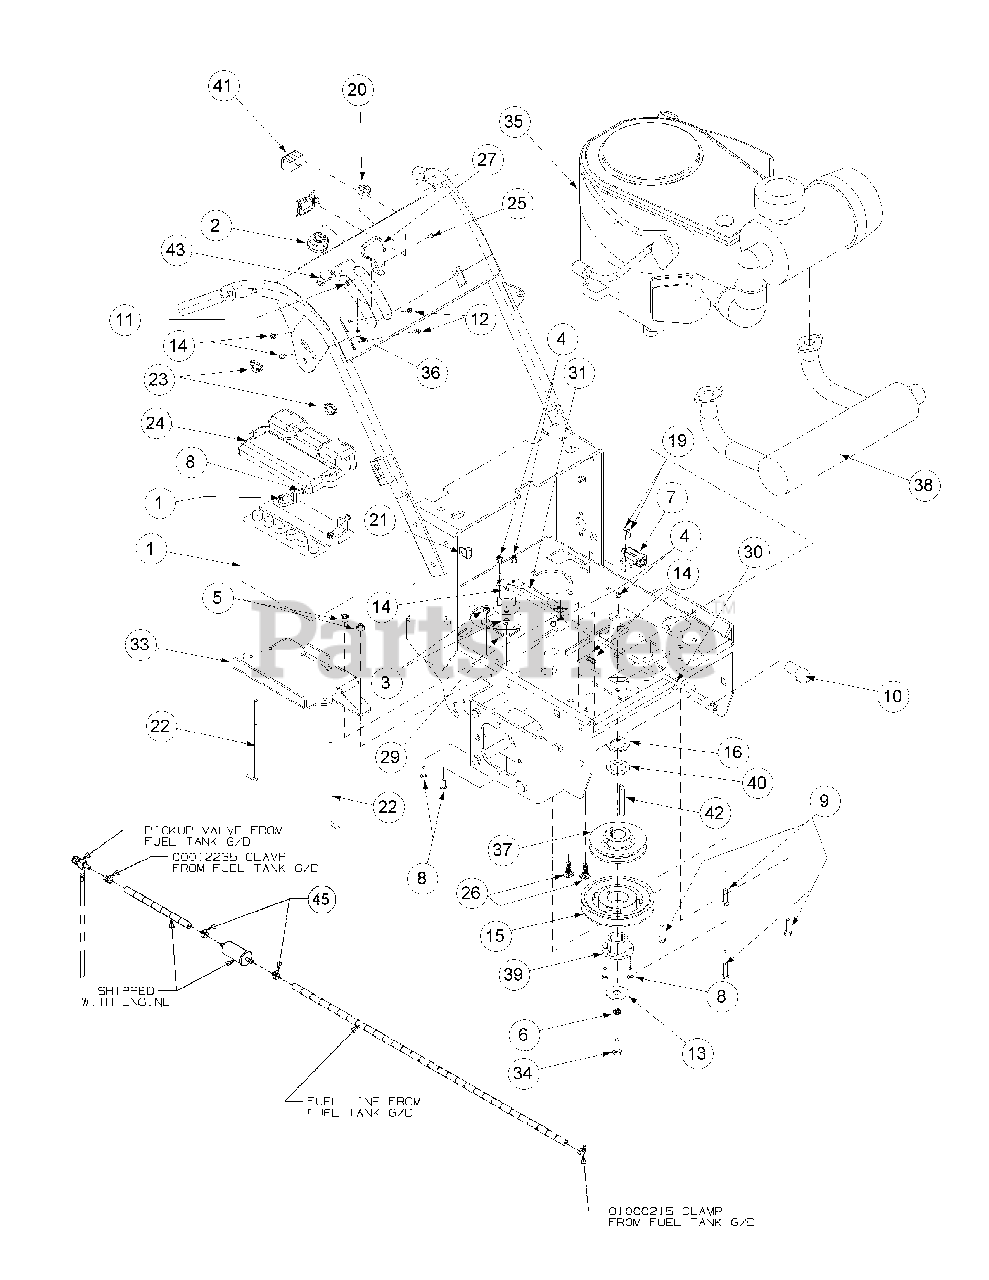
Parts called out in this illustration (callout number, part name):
1	Battery, 12V
2	Ignition Switch
3	Lock Nut Nylon Insert, 1/4-20
4	Nut, 5/16-18, Nylock
5	Lock Nut, Nylon Insert, 3/8-16
6	Lock Washer, 7/16
7	Delta Switch
8	Hex Cap Screw, 1/4-20, .75
9	Hex Cap Screw, 5/16 -18 x 2
10	Rubber Boot
11	Nut, 8-32, w/ star washer
12	Screw, Hex Washer w/Slot, 10-32 x 1/2
13	Plated Clutch Washer
14	Lock Nut, Nylon Insert, 10-32
15	Deck Pulley
16	Engine Pulley Spacer
17	Black Battery Cable 17" Long
19	Machine Screw, 10-32 x 5/8
20	Nut, w/Cap, 5/8-32 Ignition
21	Support Clamp, 3/8 OD
22	Battery Hold Down Rod
23	Wing Nut, 1/4-20 w/Bell Wash
24	Large Battery Cover
25	Machine Screw, 8-32
26	Carriage Bolt, 3/8-16 x 1
27	Throttle Control Knob
29	Magnetic Solenoid Switch
30	Red Battery Cable 24"
31	Red Battery Cable 5"
33	Battery Bracket
34	Capscrew, 7/16-20 x 1-1/4"
35	19 Hp Twin Kawasaki Kai Engine
36	Control Throttle w/detent
37	Cast Pulley, 1.125 Bore,
39	Bushing, 1-1/8
40	Special Washer
41	Hour Meter includes:
42	Key Stick, 1/4 x 1/4 x 2.75
43	Choke Cable
44	Hydro Pump Belt
45	Hose Clamp, 1/4-5/8, SS
